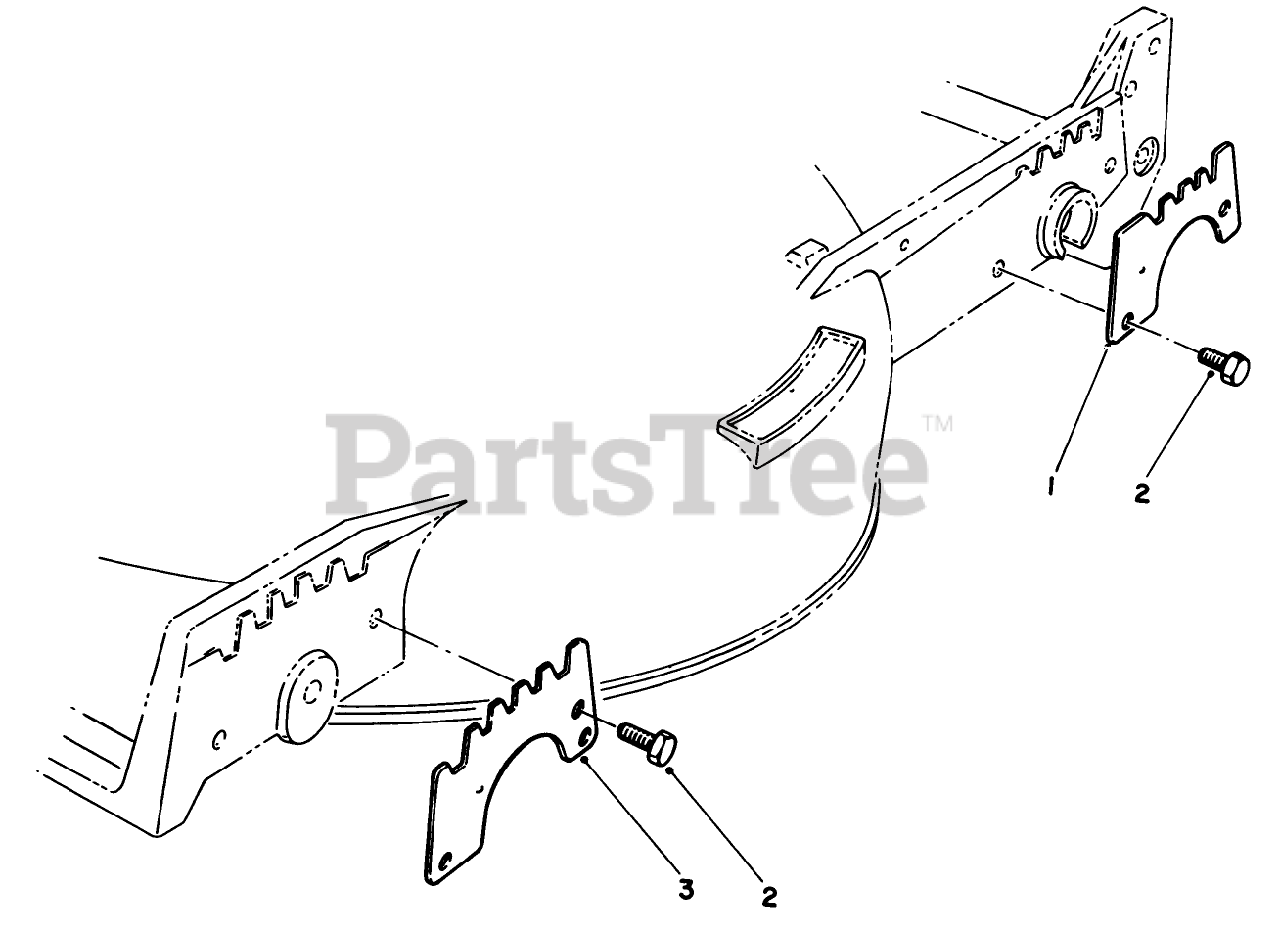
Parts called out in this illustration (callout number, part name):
1	WEAR PLATE,REAR
2	SCREW-HWH
3	WEAR PLATE
